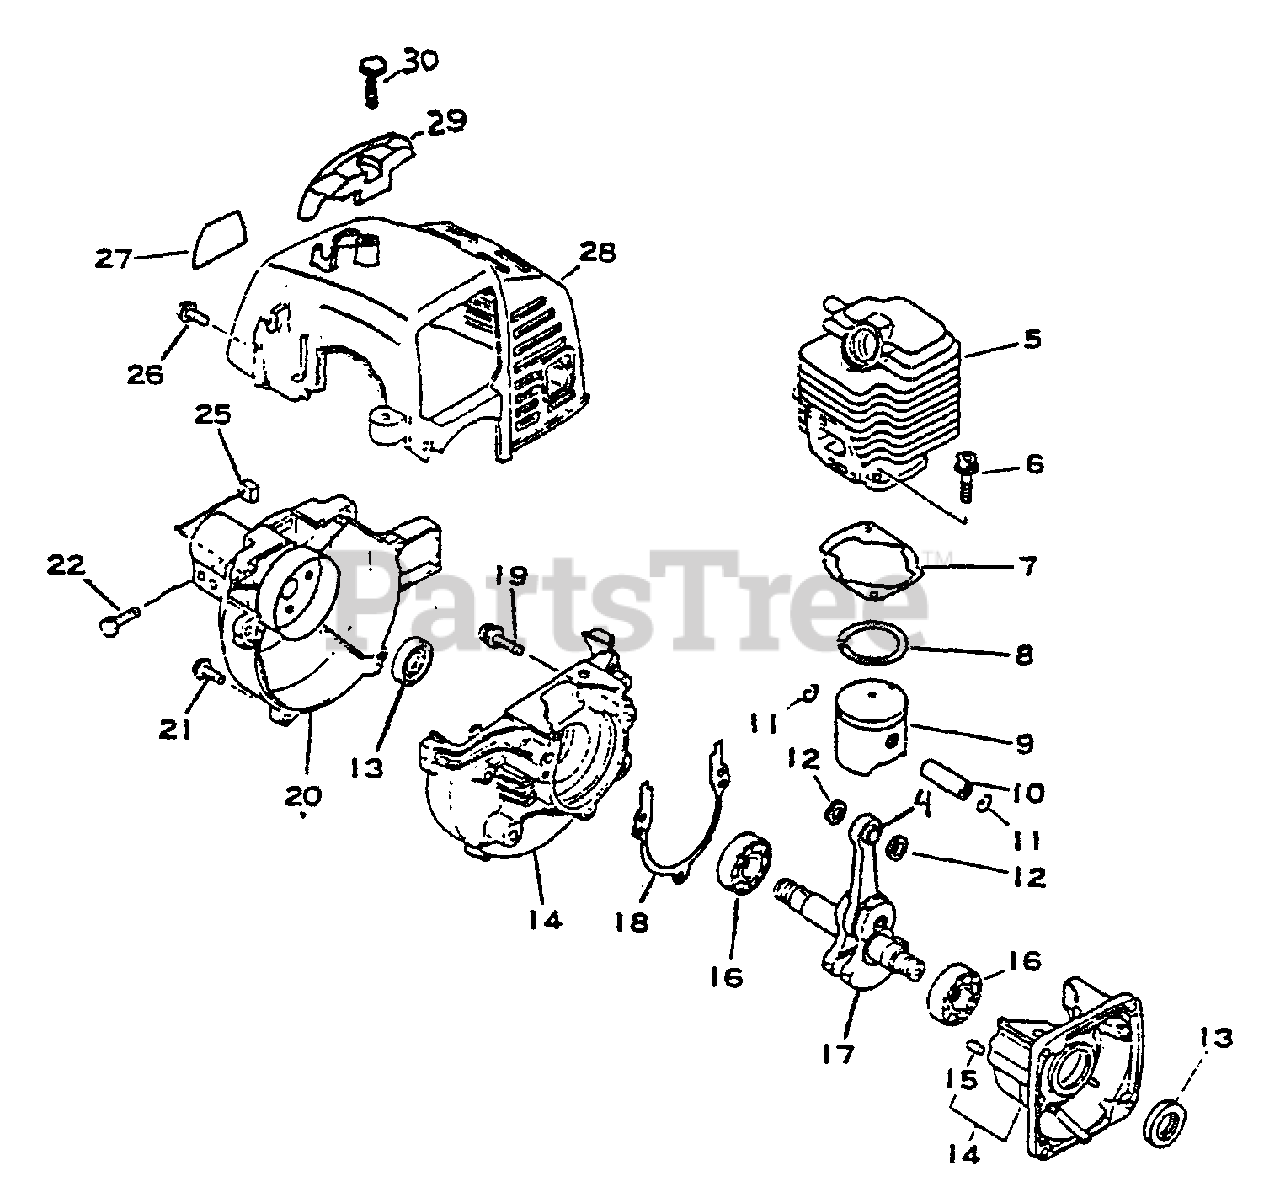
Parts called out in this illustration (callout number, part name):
4	BEARING, NEEDLE
6	BOLT 5×22
7	GASKET, CYLINDER
8	RING, PISTON
9	PISTON
10	PIN, PISTON 8
11	RING, SNAP
12	WASHER, THRUST
13	SEAL, OIL 12
14	CRANKCASE KIT
15	PIN, LOCATING 4
16	BEARING, BALL 6201
17	CRANKSHAFT ASSY
18	GASKET, CRANKCASE
19	SCREW 5×25
20	COVER, FAN
21	SCREW 5×18
22	BOLT 5×28
25	NUT M5
26	SCREW 4×12
27	LABEL - ECHO
28	COVER, ENGINE
29	GUARD, TOP - BLACK
30	SCREW 5×16
